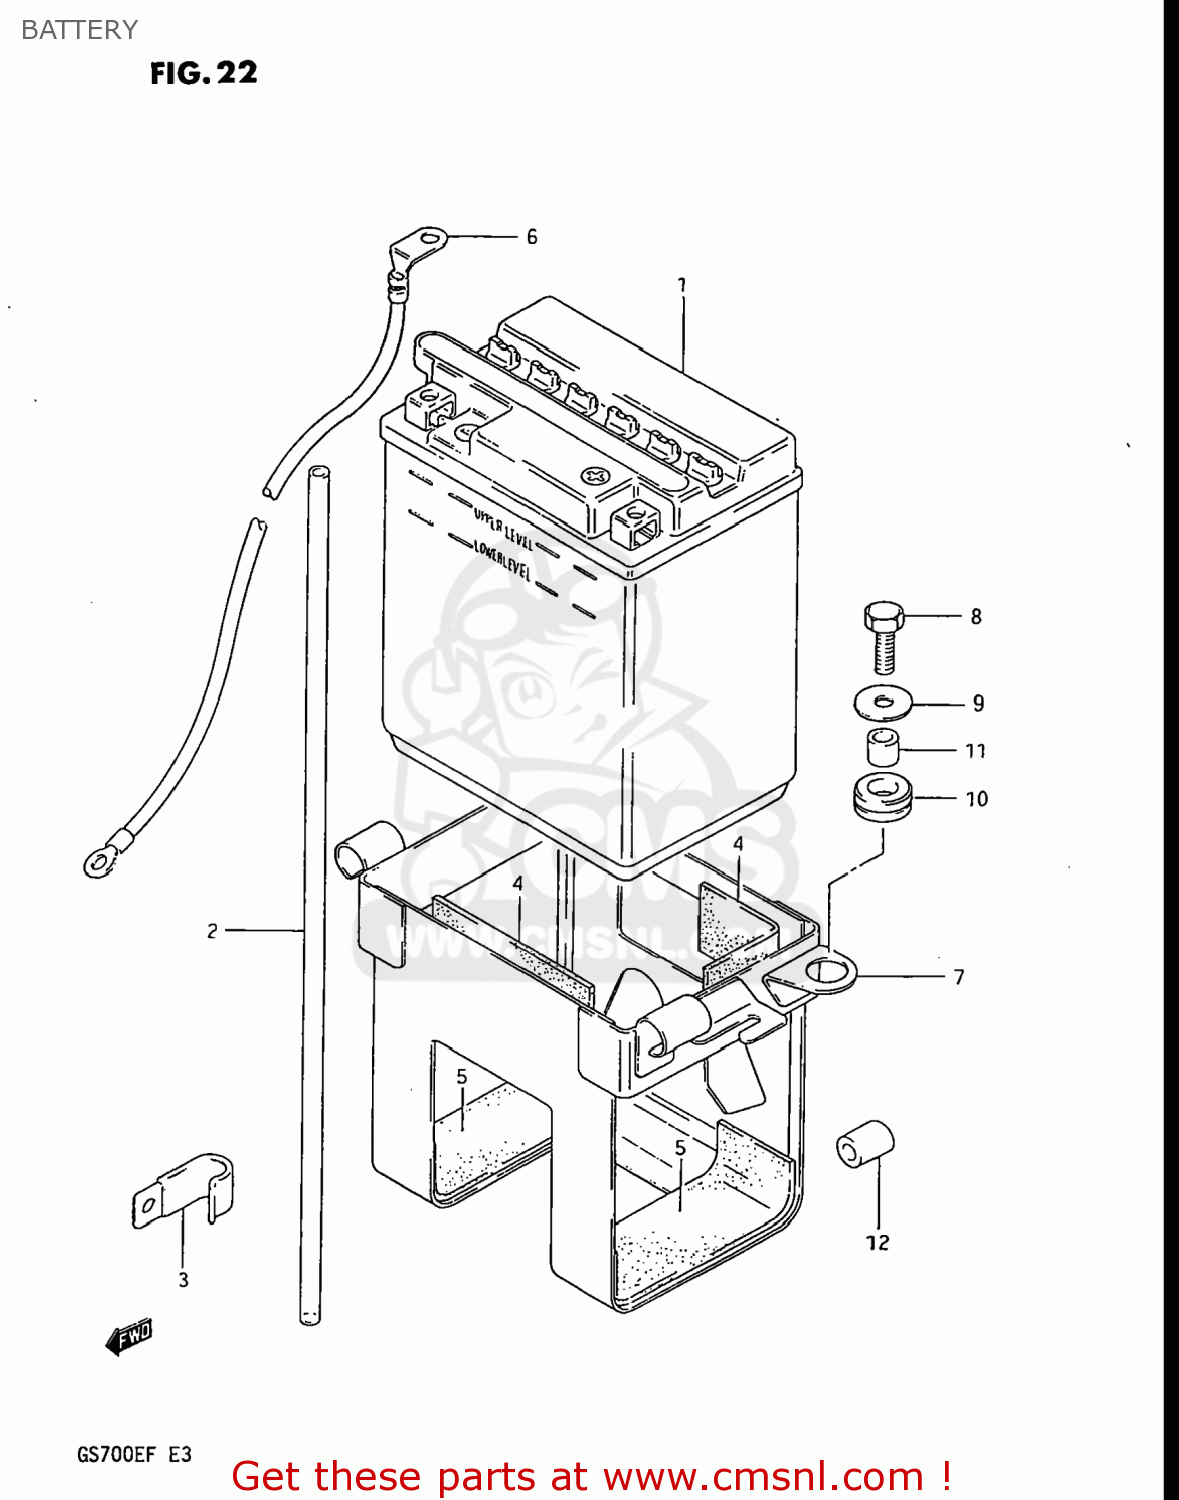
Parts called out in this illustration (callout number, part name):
1	BATTERY ASSY (12V)
2	HOSE,BATTERY EXHAUST
3	CLAMP
4	PROTECTOR(30X80X2)
5	PROTECTOR(170X95X3.0)
6	WIRE,STARTER MOTOR LEAD
7	HOLDER,BATTERY
8	SCREW
9	WASHER (6.5X20X1.2)
10	CUSHION
11	SPACER(6.1X9X7.5)
12	CUSHION
